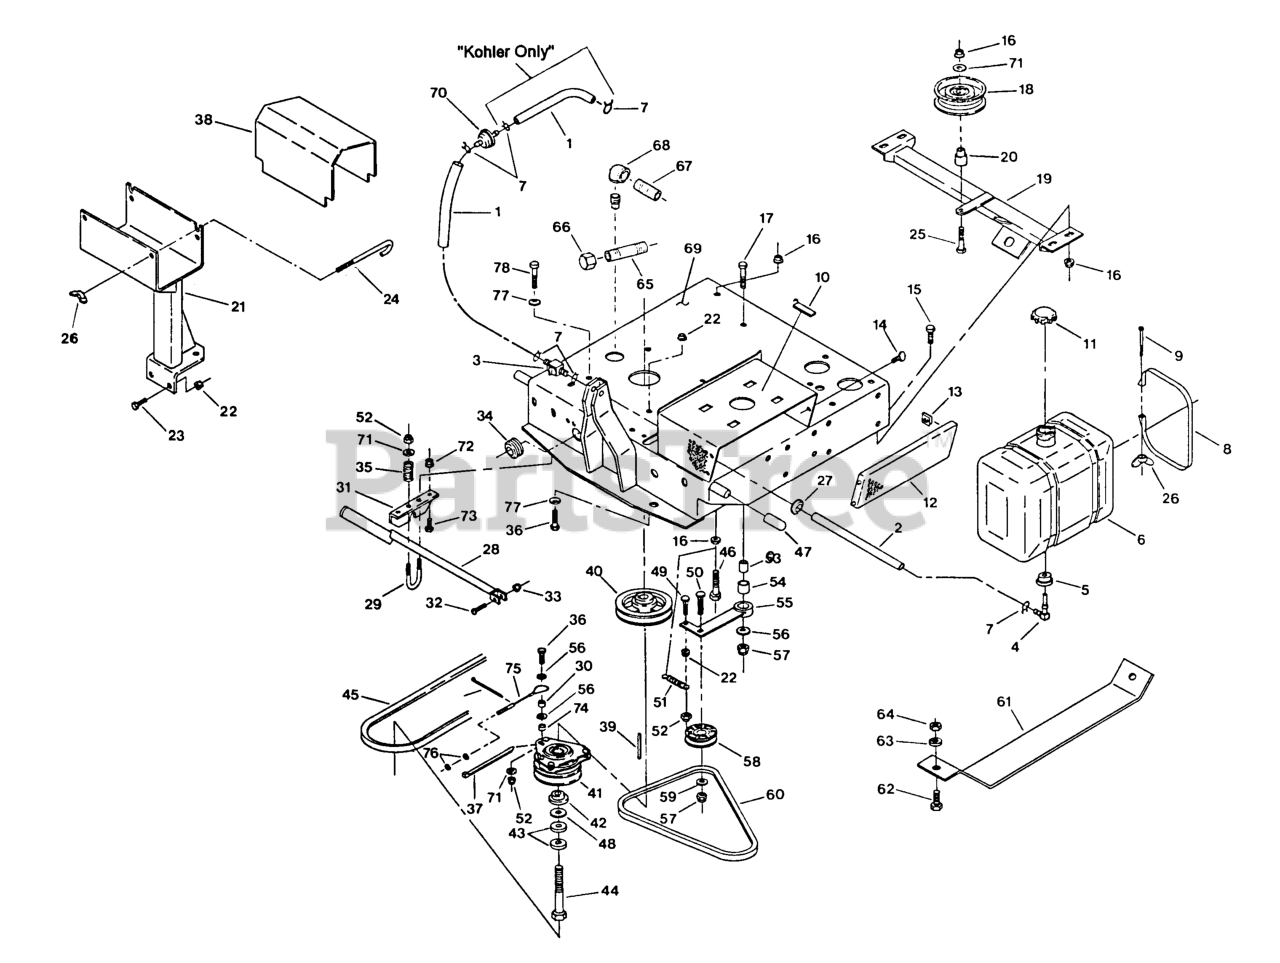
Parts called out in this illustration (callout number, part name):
1	LINE-FUEL
3	VALVE-FUEL
4	ELBOW-TANK, FUEL
7	CLAMP
10	PAD,PLASTIC TANK
11	CAP-FUEL
13	NUT,RETNR UTYP 1/4-20
14	SCREW,REGTHMB,
19	WLD,CROSSMEMBER
20	BUSHING,IDLER
21	WLD,BATTERY MOUNT
24	BOLT - HOLD DOWN
26	WINGNUT
27	GROMMET
30	SPACER,CLUTCH ANCHOR
33	NUT-LOCK, HH
34	GROMMET
35	SPRING-COMPRESSION
37	TIE-PLASTIC
40	SHEAVE,4.25 OD A
43	WASHER-SPRING
45	BELT,BLADE DRIVE
47	GRIP-LEVER, DRIVE
51	SPRING,EXTENSION
53	BUSHING,STEEL
54	BUSHING,IDLER ARM
55	WLD,IDLER ARM HYDRO
58	IDLER,PULLEY
60	BELT,A TRANS DRIVE
61	PLATE-SKID
65	NIPPLE
66	CAP-HEX
67	NIPPLE,PIPE
68	ELBOW-90 DEG
77	WASHER-SPRING
79	TIE-CABLE
